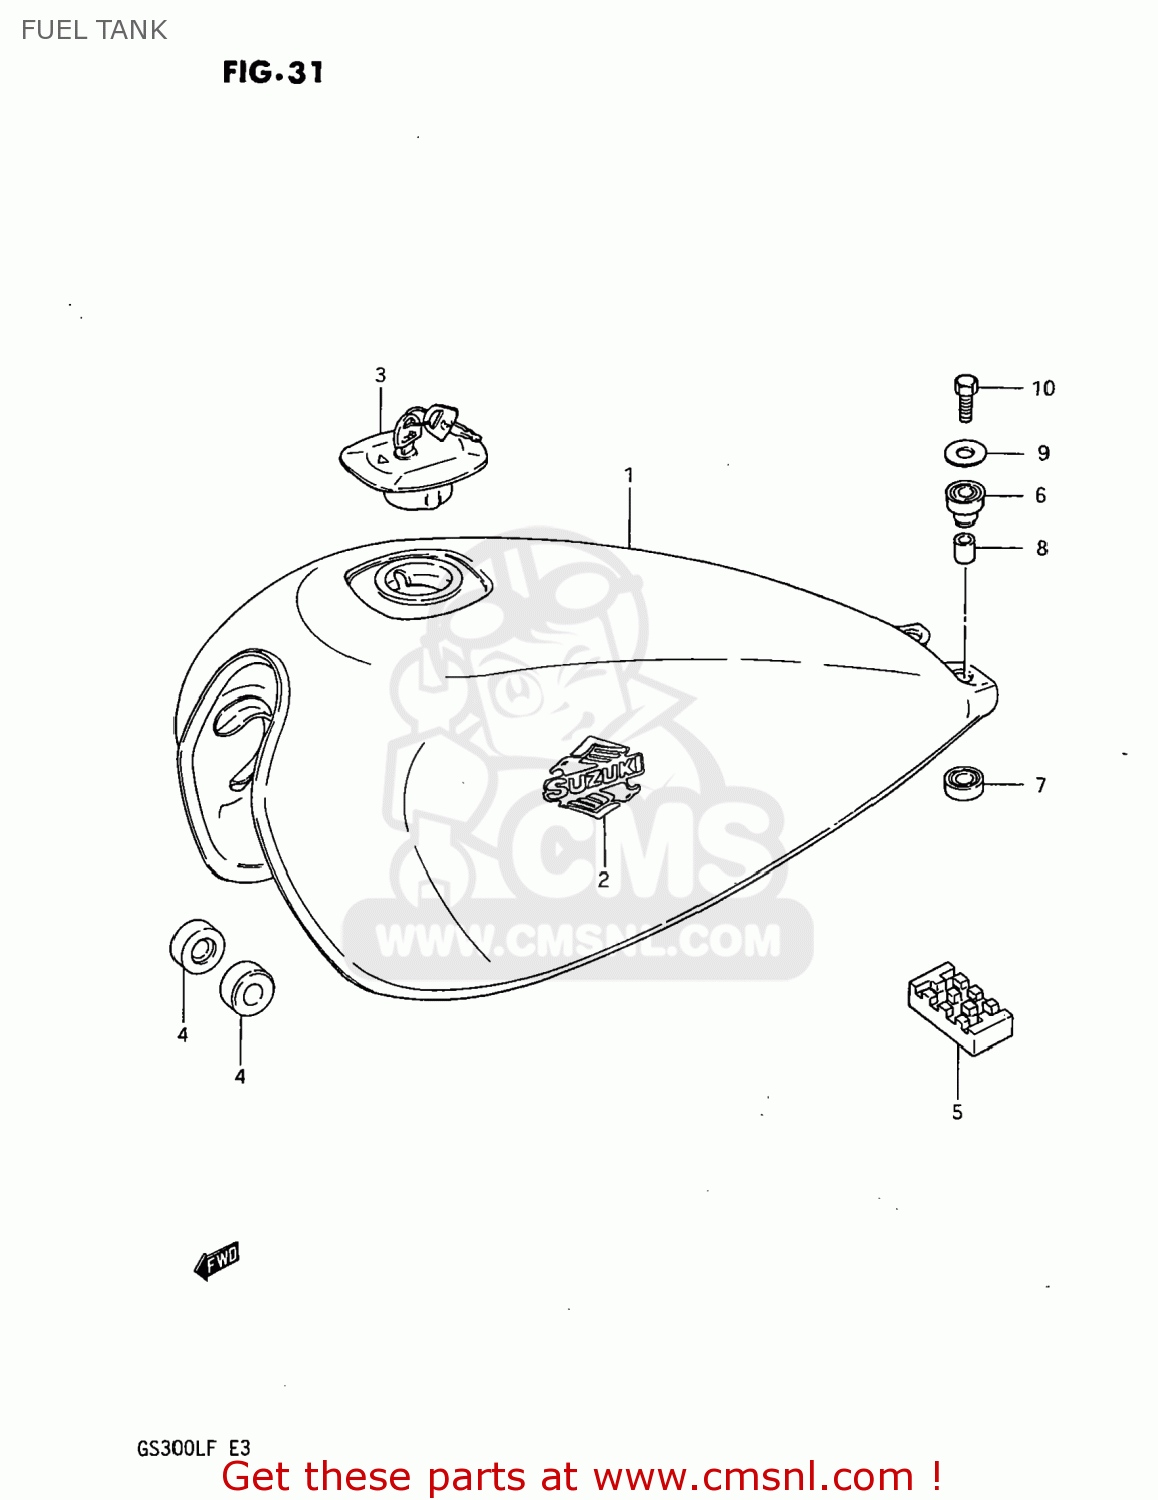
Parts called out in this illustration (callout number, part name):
1	TANK,FUEL
2	EMBLEM,FUEL TANK
3	CAP SET,FUEL TANK
4	CUSHION
5	CUSHION
6	CUSHION
7	CUSHION
8	SPACER
9	WASHER (6.5X24X1.6)
10	BOLT
